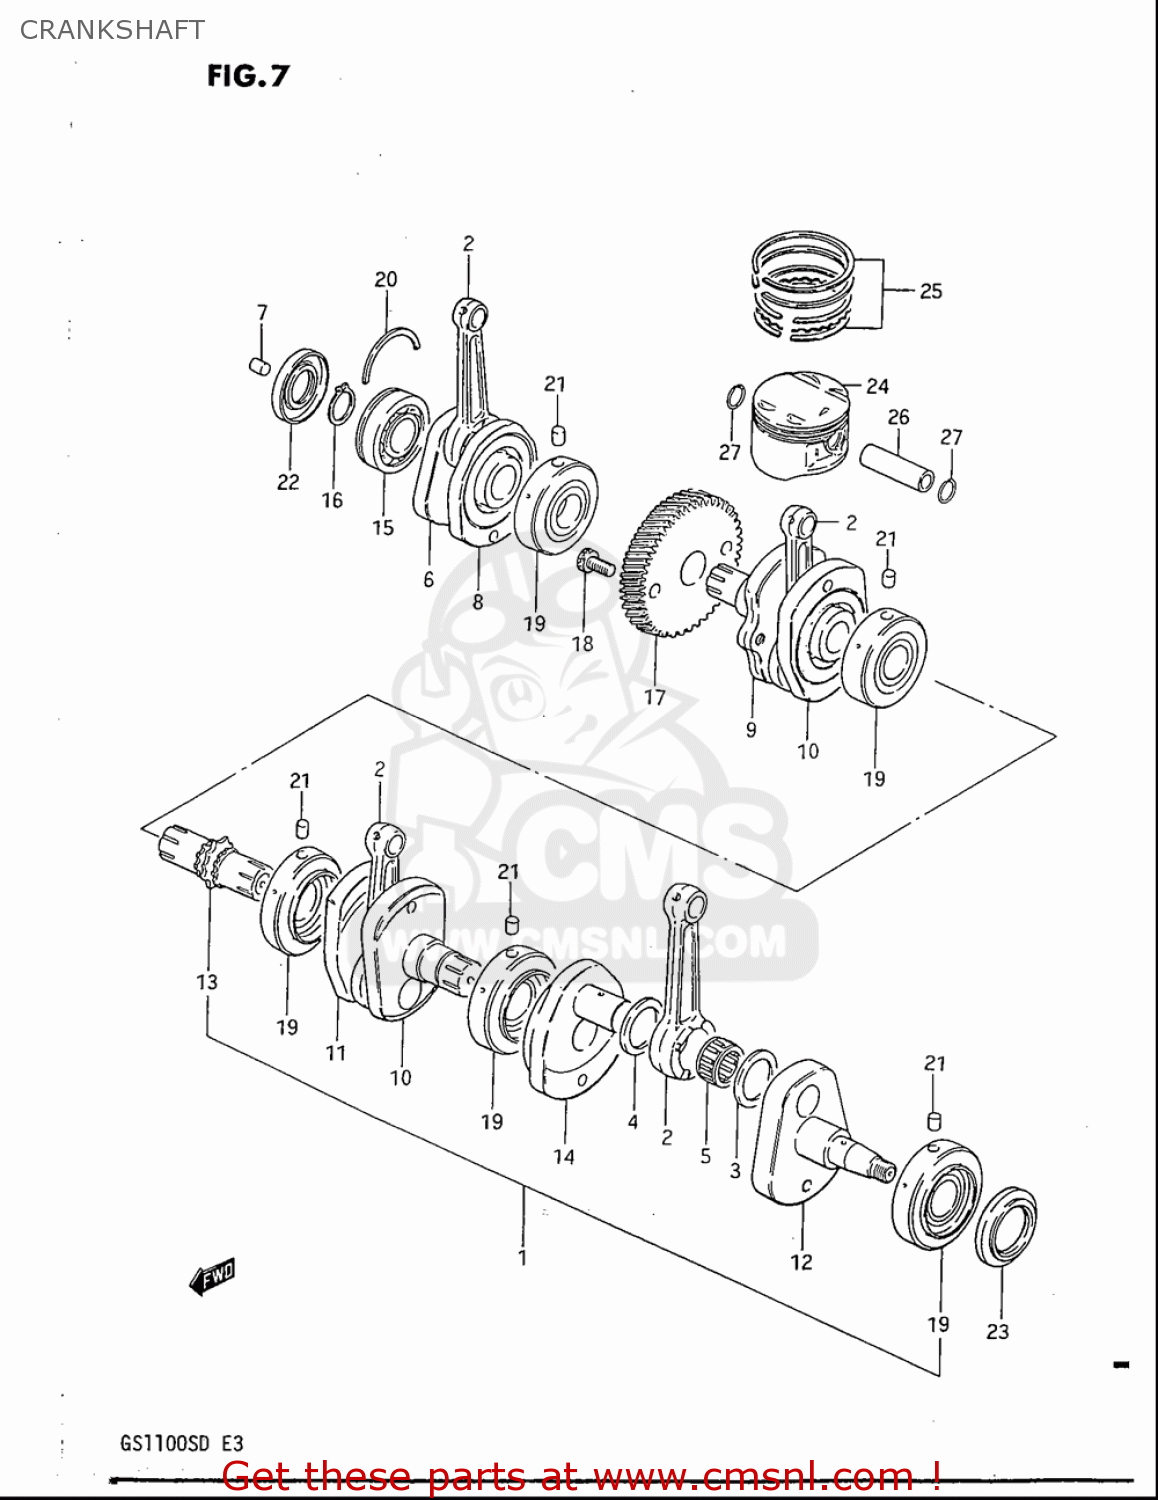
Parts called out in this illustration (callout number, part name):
1	CRANKSHAFT ASS
2	ROD,CONNECTING
3	WASHER(31X48.5X1)
4	WASHER(31X48.5X2)
5	BEARING(31X39X21)
7	PIN
8	WEB,CRANK,R
12	CRANKSHAFT,LEFT
14	WEB,CRANK,L
15	BEARING(30X72X19)
16	CIRCLIP
18	BOLT
19	BEARING(32X72X21)
20	C RING
21	PIN
22	SEAL,OIL(30X72X11)
23	SEAL,OIL(47.3X60X6.5)
24	PISTON (72.00MM)
25	RING SET,PISTON
27	CIRCLIP,PISTON PIN
